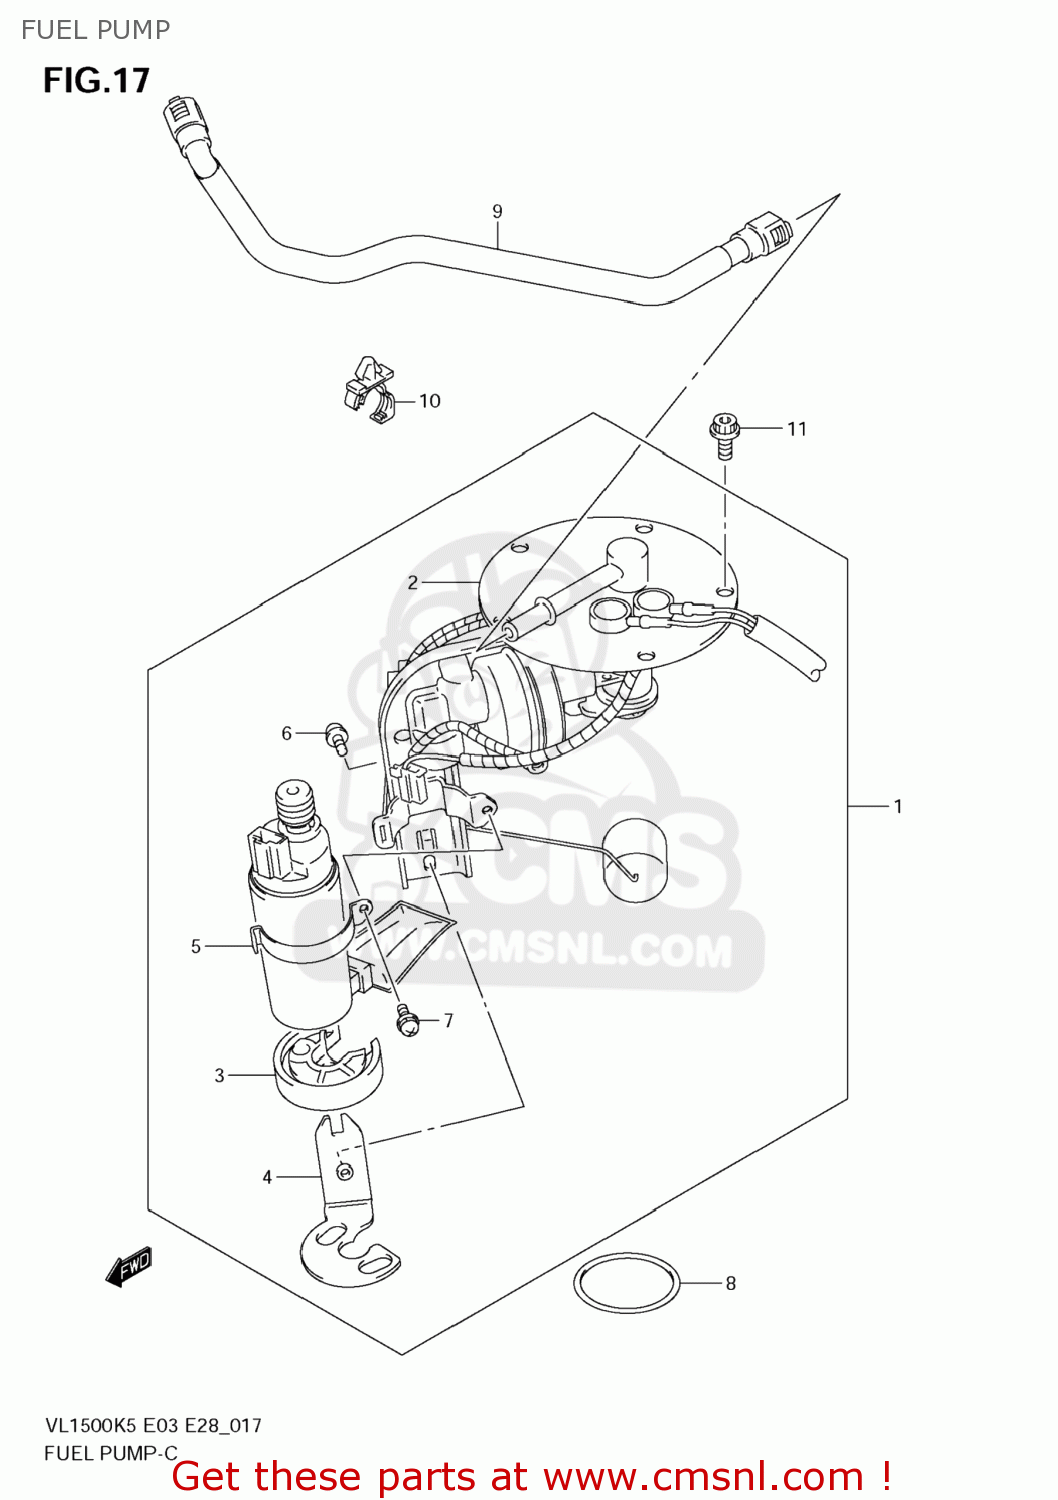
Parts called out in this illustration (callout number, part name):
1	PUMP ASSY,FUEL
2	PLATE ASSY
3	CUSHION
4	HOLDER,FUEL PUMP
5	BAND,FUEL PUMP
6	SCREW
7	SCREW
8	O RING,FUEL PUMP
9	HOSE, FUEL
10	CLAMP
11	BOLT
